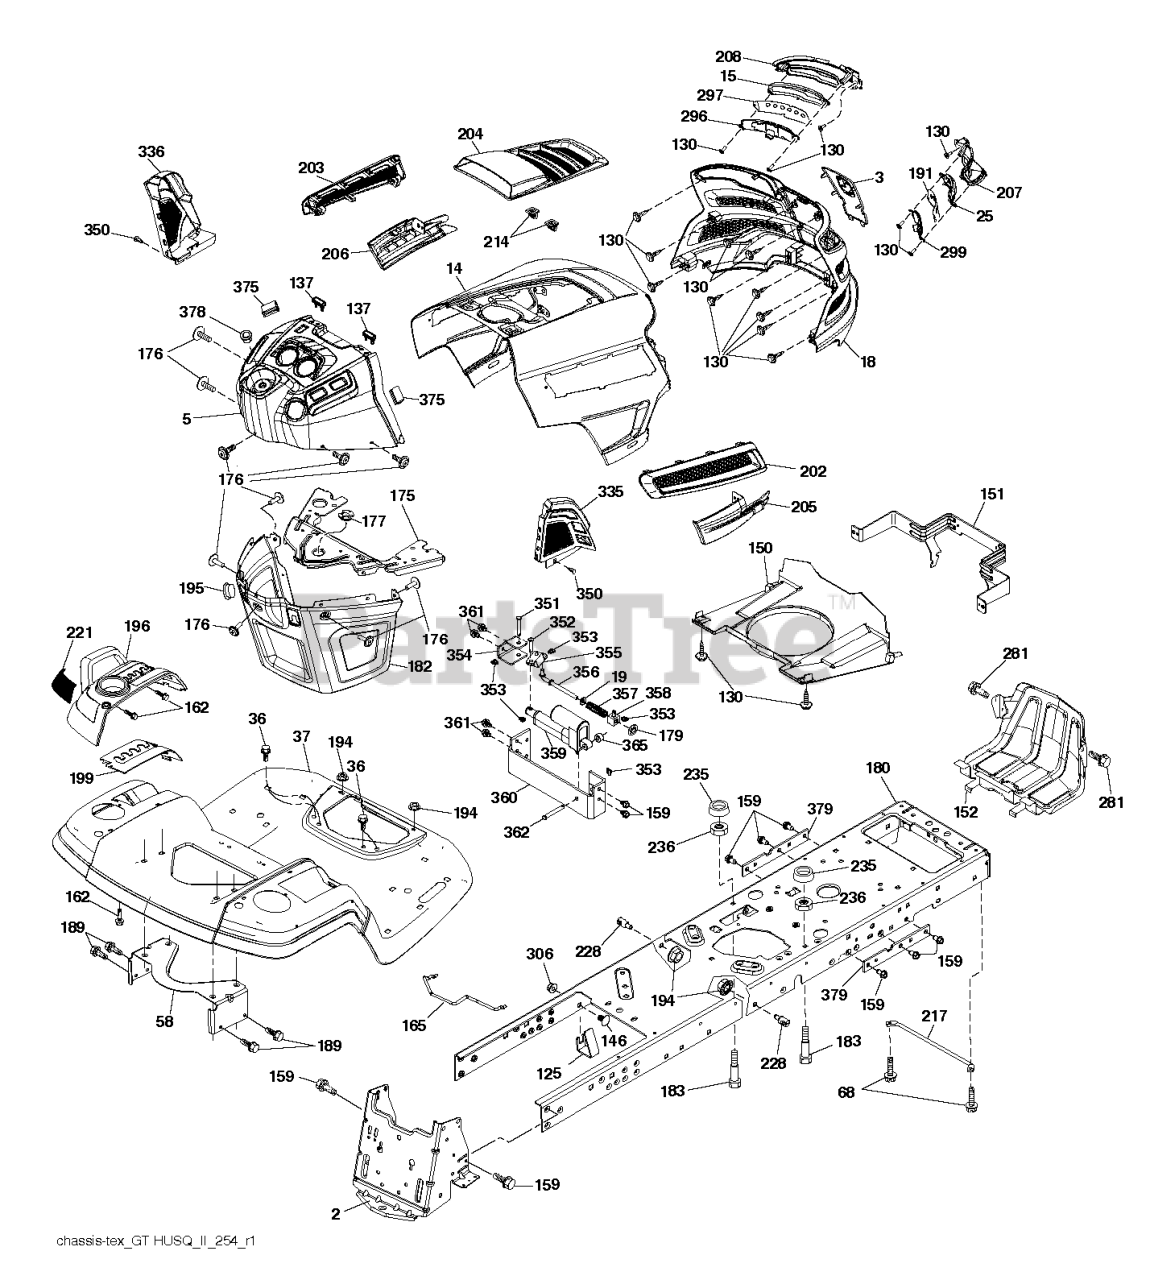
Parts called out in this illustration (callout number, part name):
2	DRAWBAR.STGT
3	APPLIQUE.SUBASM.GT.HUSQ.II
5	DASH.UPR.GT2.DUAL.RD.PTO.MC
14	HOOD.ASM.HUSQVARNA.GT.TEX.ORAN
15	LED LIGHT.LH
18	GRILLE SUBASM.GT.II.LOW.HDLGHT
19	WASHER
25	LENS.RH
36	SCREW 5/16"
37	FENDER HUSQVARNA GT MS668 - HU
58	BRKT.SUPPORT.FNDR/TANK
68	SCR 5/16-18 X 1/2 SELFTAP ZN
125	CLIP.FUEL.LINE
130	SCREW.#10 X 0.750.BOS
137	BUMPER DASH
146	BOLT.RDHD.SHT.SQNK.3/8-16X5/8
150	AIR.DUCT.GTV.BLACK
151	BRACKET.PIVOT.HOOD.GT.HUSQ.II
152	SHIELD.BROWNING.PNT.GT.V2
159	SCREW, 3/8-16X3/4
162	SCREW.HI-LO.CONSOLE
165	SUPPORT.TANK.REAR.B/TE
175	PLATE.PNT.CROSSMEMBER.HUSQ/PRE
176	SCREW.#10-24X5/8.RN.QU
177	BUSHING STEERING
180	CHASSIS.LT/GT.BOLTED
182	DASH.LOWER.COMMON.12V.ADAPTOR
183	BOLT.5/16-18X1-1/4 FULL THD
189	SCREW
191	INSERT INFLECT.RH
194	NUT LOCK HEX FLANGE 5/16-18
195	PLUG.HOLE.DASH.LOWER.12V.BLK
196	CONSOLE.ASM.DECKLIFT.HUSQGT.DL
199	PLATE.DECK.LIFT.HUSQVARNA.GT
202	VENT.SIDE.RH.GT.HUSQ.II.
203	VENT.SIDE.LH.GT.HUSQ.II.498
204	VENT.TOP.HUSQ.GT2
205	SIDE.TRIM.RH.GT.HUSQ.II
206	SIDE.TRIM.LH.GT.HUSQ.II.GRAY
207	BEZEL GT2 LED RH W/ LOWER.ATT
208	BEZEL GT2 LED LH W/ LOWER ATT
214	CLIP.RETAINER.TINNER.
217	ROD.PIVOT.HOOD
221	REFLECTOR.LH.TEX GT HU
228	STUD.FASTNER.W/ANTI-ROTATE
235	SPACER FENDER
236	NUT.CENTERLOCK.5/16-
281	SCREW 3/8-16X1
296	LED LIGHT.LH
297	INSERT REFECT LH
299	LED LIGHT.RH
306	NUT LOCK FLG 3/8-16 UNC
335	COVER.LOWER.DASH.RH.BLACK
336	COVER-LH.LOWER.DASH.GT2.BLACK
350	CLIP.X-MAS.TREE
351	PIN.CLEVIS.375X2.125
352	PIN.CLEVIS.(.375 X 1.25)
353	CLIP RETAINER
354	SUPPORT.BELLCRANK
355	BELLCRANK.PIVOT.LOCK.DIFF
356	LINK.LOCK.DIFF
357	SPRING.COMPRESSION
358	GUIDE.SWIVEL
359	ACTUATOR.ELECTRIC
360	BRACKET.ACUATOR
361	SCREW LT.3/8-46X5/8
362	PIN.CLEVIS.(.375 X 2.42)
365	SPACER.NYLON.75" X .4375
375	BUMPER CLIP-ON. DASH 1"
378	BUSHING FLANGE; PLASTIC
379	Husqvarna TBD
